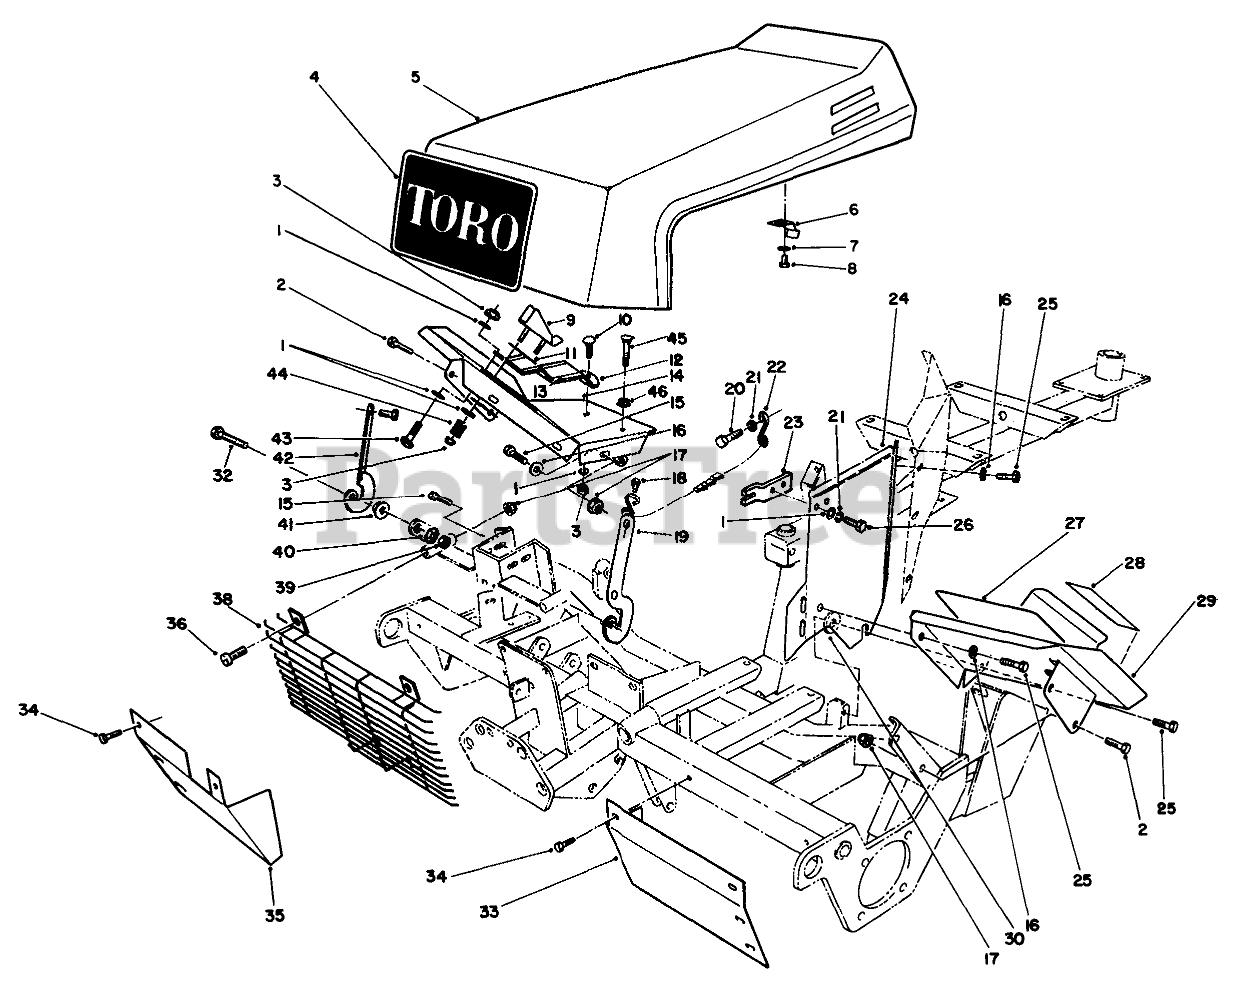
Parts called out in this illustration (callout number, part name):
1	Hood
2	REAR HOOD FOAM STRIP
3	Grille-Rear Panel
4	WASHER-FLAT
5	Screw
6	GM 220 DECAL
7	WASHER-SPRING
8	Link Hood
9	SCREW-HH
10	PivotPin L.H.
11	SCREW-HH
12	Tie Hood
13	WASHER-LOCK
14	NUT-HEX
15	WASHER-FLAT
16	SCREW-SHOULDER
17	NUT-HEX
18	NUT-HF
19	HOOD TRIM
20	NUT-HEX
21	WASHER-LOCK
22	CLAMP-SLOTTED
23	SCREW-SHWH
24	HOOD TRIM
25	FRT HOOD FOAM STRIP
26	HOOD TRIM
27	TRIM-HOOD
